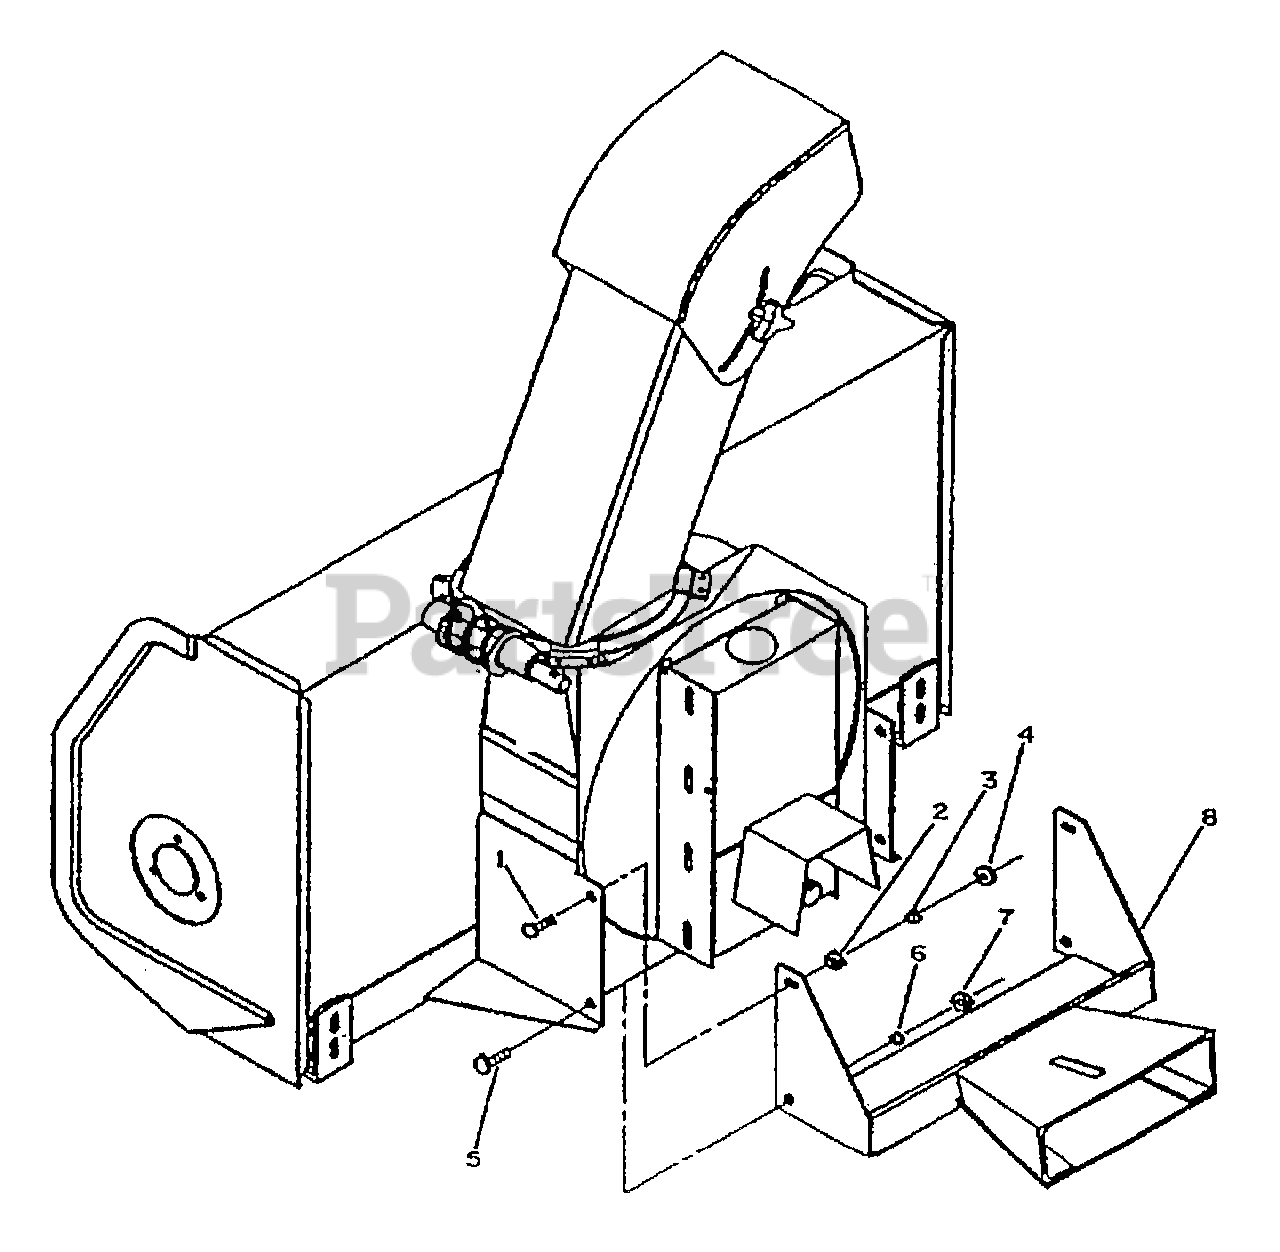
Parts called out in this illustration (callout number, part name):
1	SCR-HH 3/8-16X1.0 G5 ZP
2	WASHER-.986X.437X.083 ZP
3	WASHER-LK .375 @ DEPL
4	NUT-HEX 3/8-16 ZP
5	SCR-HH 1/2-13X1.0 G5 ZP
6	WASHER-LK .5
7	NUT-HEX JAM 1/2-13
8	QUICK HITCH-FEMALE
